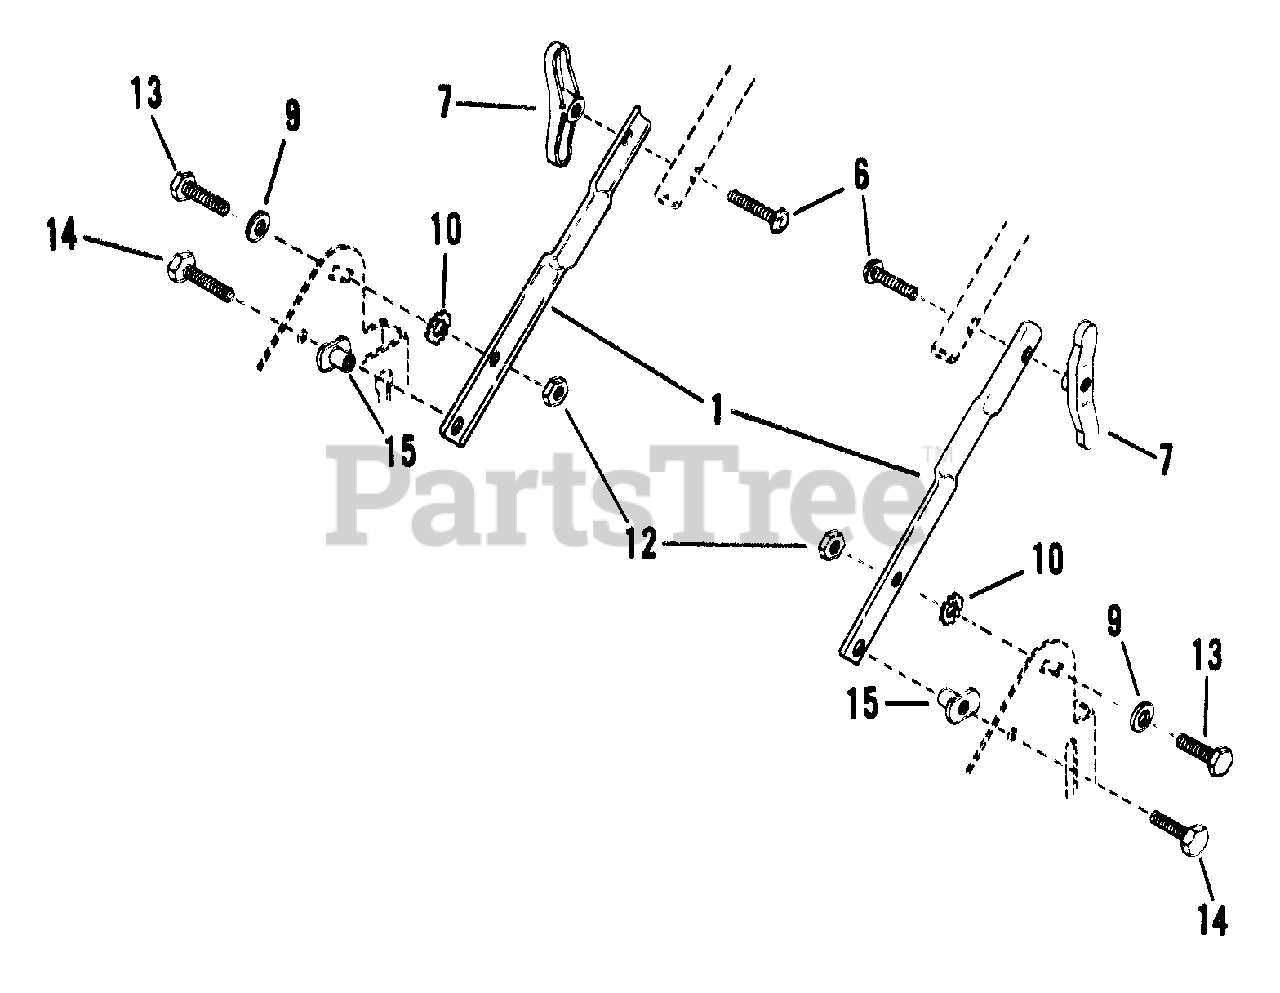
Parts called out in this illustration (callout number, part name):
1	HANDLE, Lower
6	BOLT, 1/4-20 x 1-3/4" Short Neck Carriage
7	NUT, 1/4-20 Wing
9	WASHER, 5/16 Flat
10	WASHER, 5/16 Internal-External Tooth Lock
12	NUT, 5/16-24 Hex Center Lock
13	SCREW, 5/16-24 x 3/4" Hex Cap
14	SCREW,5/16-18 x 1/2" Hex Cap
15	T-NUT, 5/16-18
